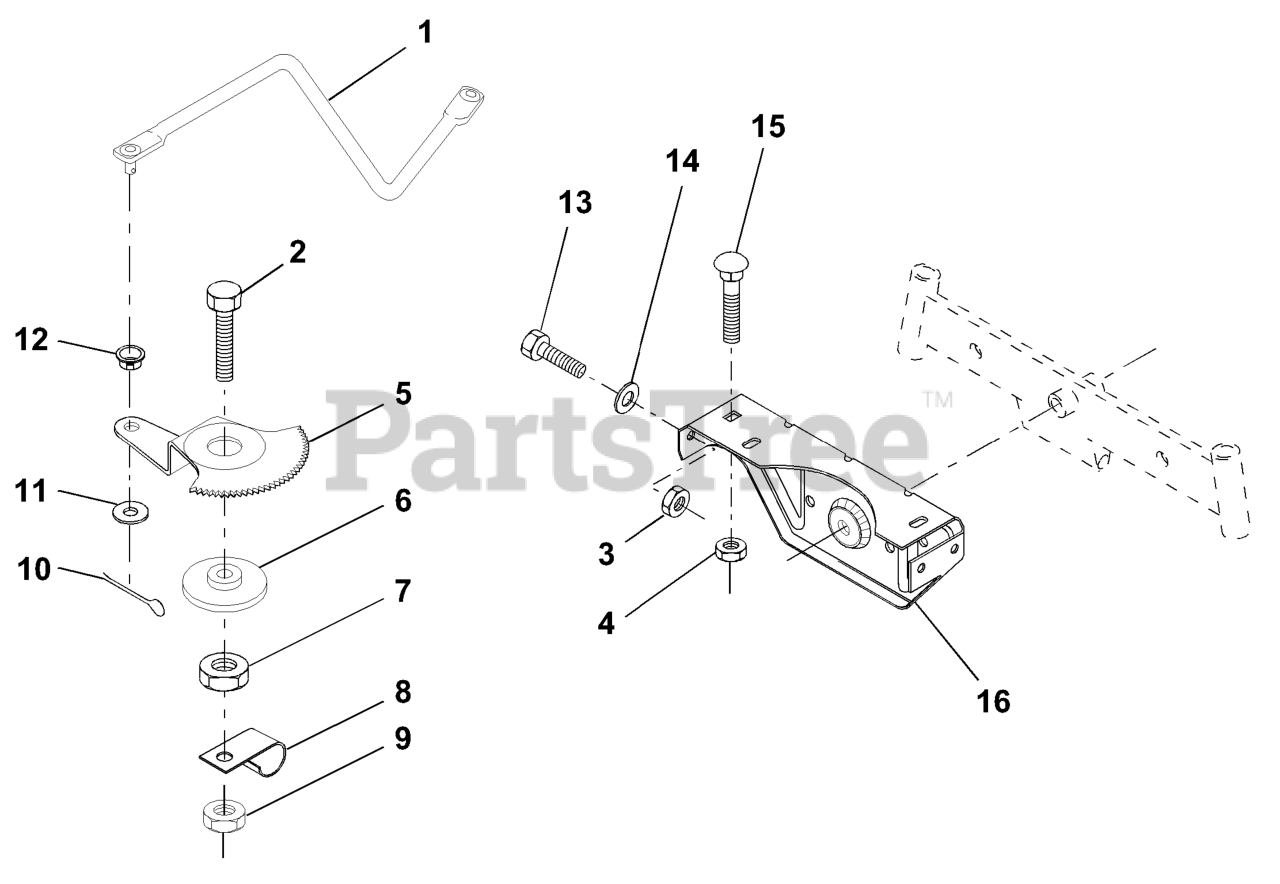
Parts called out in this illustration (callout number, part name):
5	GEAR SECTOR
7	NUT
8	CLIP INSULATOR
9	NUT LTV
10	COTTER PIN
11	WASHER
12	BUSHING.DRAGLINK (2 2)
13	BOLT
14	WASHER
15	BOLT
17	SUPPORT/AXLE FRONT
21	LOCKNUT
